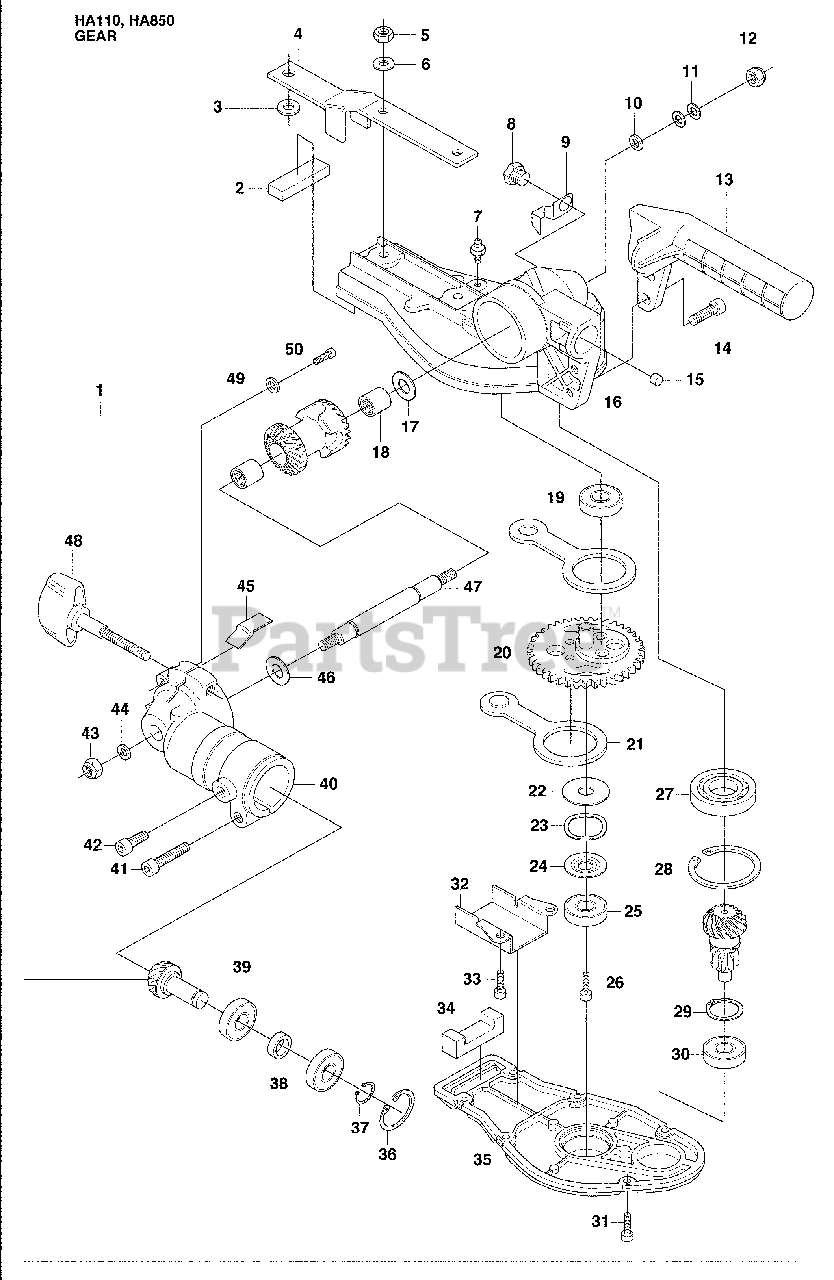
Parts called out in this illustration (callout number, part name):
2	Gasket
3	Washer, 6.4 X 18 X 1.5
6	Washer, 7/32 X 1/2 X 16 Gauge
7	GREASE NIPPLE
10	Washer, M6
12	Hex Flange Nut, M6
13	Cutting Deck Handle
14	Screw, IHSCM
16	Gear Housing
18	Support Bushing
19	Ball Bearing
21	Connecting Rod
25	Ball Bearing
26	Screw, MC6S 5 X 10
27	Ball Bearing
28	Retaining Ring
29	Retaining Ring
30	Ball Bearing
31	Socket Head Capscrew, M4 X 0.7 X 12
33	Screw, MC6S 4 X 8
34	Gasket
36	Retaining Ring
37	Retaining Ring
39	Ball Bearing
40	Gear Housing
41	Screw, M5 X 25 Pl Hsc Ih X
42	Screw, M5 X 12 Ms Hcs Ih X
43	Hex Flange Nut, M6
44	Washer, M6
49	Washer, 7/32 X 1/2 X 16 Gauge
50	Screw, MC6S 5 X 16
